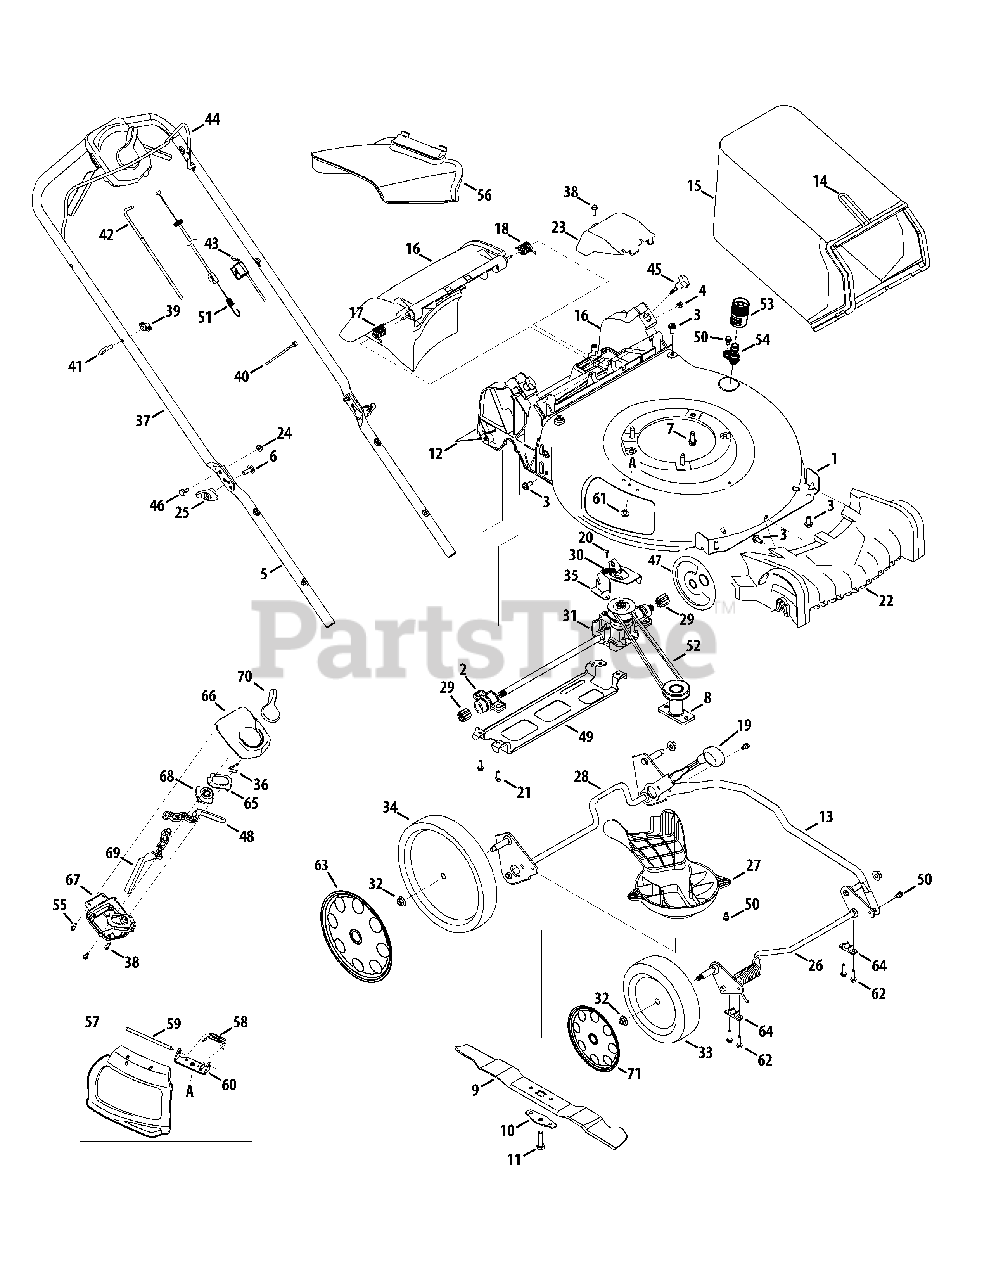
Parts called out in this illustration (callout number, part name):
1	Deck , 21"
2	Bearing Assembly
3	Screw, 5/16-14 x .750
4	Nut, Sq., 1/4-20
5	Lower Handle
6	Carriage Screw ,5/16-18
7	Screw, 3/8-16 x 1.00
8	Blade Adapter
9	Mulching Blade
10	Blade Bell Support
11	Screw, 3/8-24 x 1.50
12	Trailing Shield
13	Cross Bracket
14	Grass Catcher Frame
16	Rear Discharge Door Assembly
17	Torsion Spring - RH
18	Torsion Spring - LH
19	Adjustment Lever Knob
20	Screw, Hex Washer, .159 x .43
21	Screw, 1/4-15 x 1.25
22	Front Cover
23	Transmission Cover
24	Nut, Flange Lock, 1/4-20
26	Front Axle Assembly
27	Engine Baffle
28	Rear Axle Assembly
29	Spur Gear, 9T
30	Exten. Spring, 2.405
31	Transmission Assembly
32	Flange Lock Nut, 3/8-16
33	Front Wheel
34	Rear Wheel
38	Screw, 1/4-15 x .750
40	Cable Tie
41	Rope Guide
42	Drive Cable
43	Control Cable
45	Wing Nut
46	Sldr. Screw, .375 x .126 x 1/4-20
47	Wheel Dust Cover
48	Control Lever LH
49	Rear Support Bracket
50	Screw, Shldr., 1/4-20 x .50
51	Speed Adjustment Cable
53	Water Nozzle Adapter
54	Water Nozzle
55	Screw, Shldr, 1/4-15 x .970
56	Side Discharge Chute
57	Mulch Plug (Incl. 58-60)
58	Torsion Spring
60	Chute Deflector Bracket
61	Screw, 1/4-20 x .500
62	Screw, 1/4-15 x 1.000
64	Bushing, Lock, .505 Dia. X .62
65	Cable Adjust Plate
66	Upper Housing
67	Lower Housing
68	Speed Adjust Actuator
69	Control Lever RH
70	Speed Select Lever
71	Hubcap, 8"
